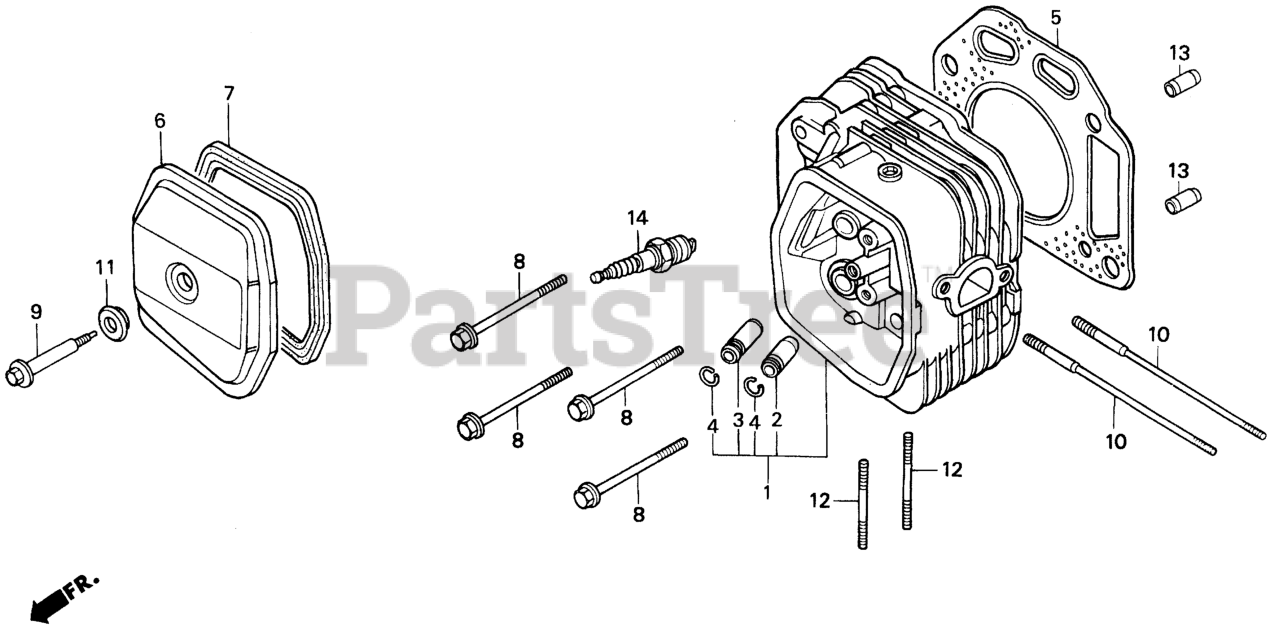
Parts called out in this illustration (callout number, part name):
1	CYLINDER HEAD
2	GUIDE, VALVE (OS)
4	CLIP, VALVE GUIDE
5	GASKET, CYLINDER HEAD
6	COVER, HEAD
7	GASKET, CYLINDER HEAD COVER
8	BOLT, FLANGE (10X85)
9	BOLT, HEAD COVER
10	BOLT, STUD (8X150)
11	WASHER, HEAD COVER
12	BOLT, STUD (8X22)
13	PIN A, DOWEL (12X20)
14	SPARK PLUG (BPR5ES) (NGK)
14	SPARK PLUG (W16EPR-U) (DENSO)
